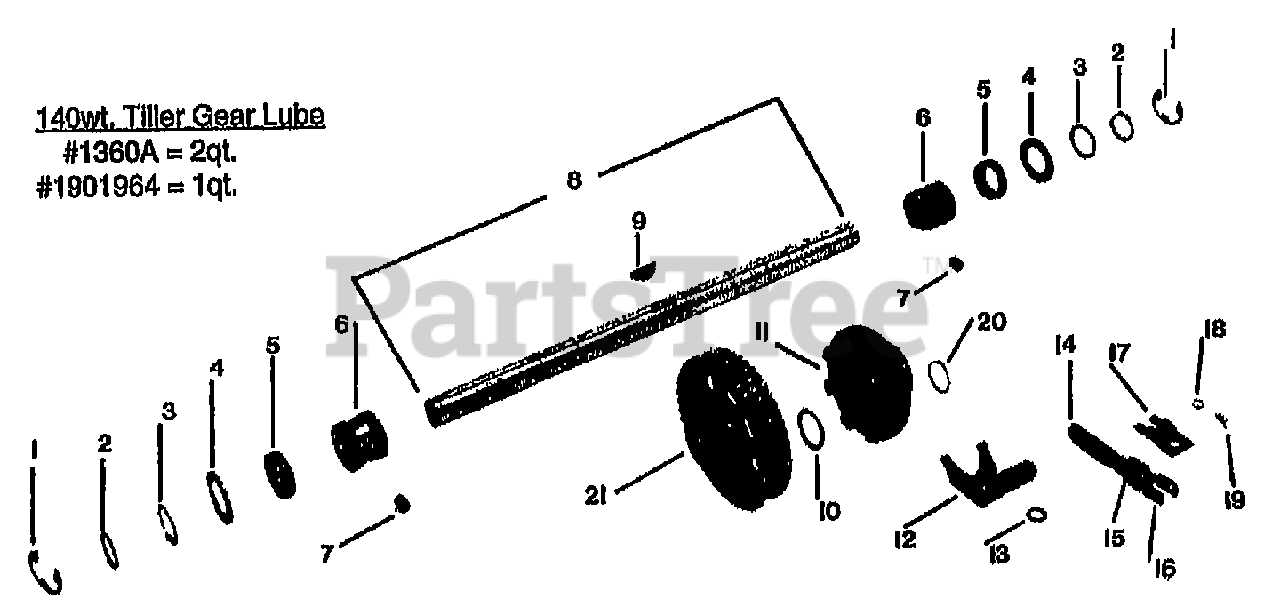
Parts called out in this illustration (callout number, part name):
1	RING-RETAINING 5133-989
2	RING-HEAVY EXT .906 ID
3	SHIM SET-WHEELSHAFT-HORSE
3	SHIM-1.375X1.015X.03
3	SHIM-1.375X1.015X.015
3	SHIM-1.375X1.015X.01
4	SHIM-1.75X1.013X.09
5	SEAL-OIL WHEELSHAFT
6	BUSHING-1.503X1.005X1.187
7	SCR-SS 3/8-16 X .5 (CP)
8	WHEELSHAFT W/KEY-PONY 2 (INCL.# 9305 KEY)
9	KEY-HI PRO .25X1.062
10	SHIM-1.375X1.015X.062
11	CLUTCH-MACH
12	YOKE-RIVETED HT
13	RING-O .625 X .438
14	SPLINE/YOKE-HT
15	PIN-SPIROL .188 X .875
16	UNIVERSAL (U-JOINT)
17	PLATE-FRICTION
18	WASHER-LK .25 ZP
19	SCR-HH 1/4-20X.5 GR5 YEL
20	RING-RETAINING 5100-100
21	GEAR-WORM
